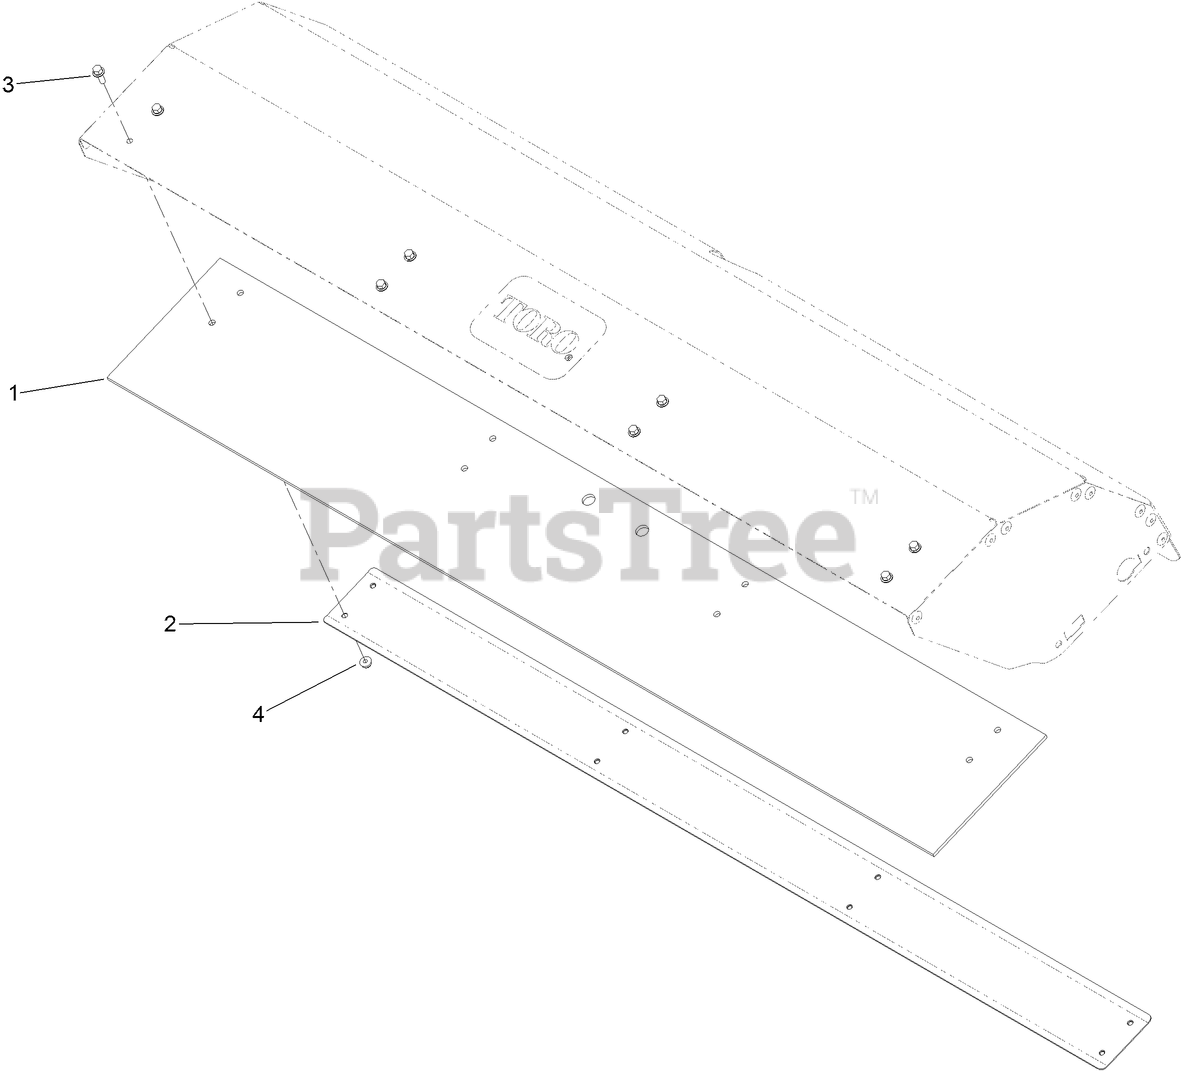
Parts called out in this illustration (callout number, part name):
1	FLAP-UPPER
2	FLAP-LOWER
3	SCREW-HHF
4	NUT-HF
